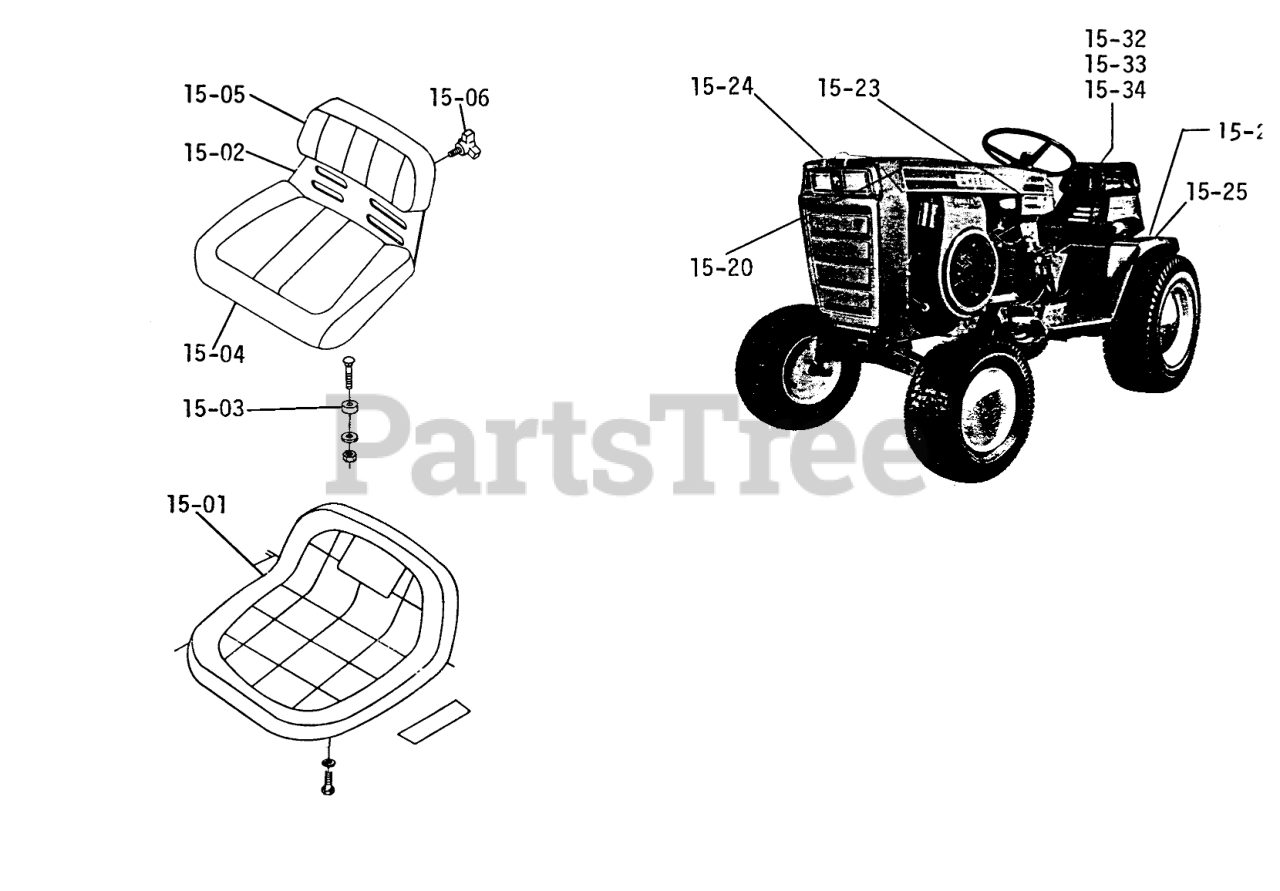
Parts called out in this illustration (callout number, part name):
15-01	Seat
15-01	Bolt Hex 5/16-18
15-01	Lockwasher
15-01	Nut-Hi Crown
15-02	Seat Base
15-03	Spacer
15-03	Bolt-Car. 5/16-18 x 1
15-03	Nut-Nylok
15-04	Cushion Seat
15-04	Bolt, 1/4-20 Whizlock
15-05	Back Cushion
15-06	Knob 8 HP
15-06	Lockwasher
15-06	Nut-Hi Crown
15-06	Bolt Hex 5/16-18
15-20	Decal-Hood
15-23	Decal-Raider 10
15-23	Decal-Raider 8-6 Speed
15-23	Decal-Raider 14-6 Speed
15-23	Decal-Raider 12
15-24	Decal-Racing Stripes
15-25	Decal
15-26	Reflector
15-32	Deal-Seat Latch
15-33	Decal Shift Pattern
15-34	Decal-Caution (lower hoodstand)
